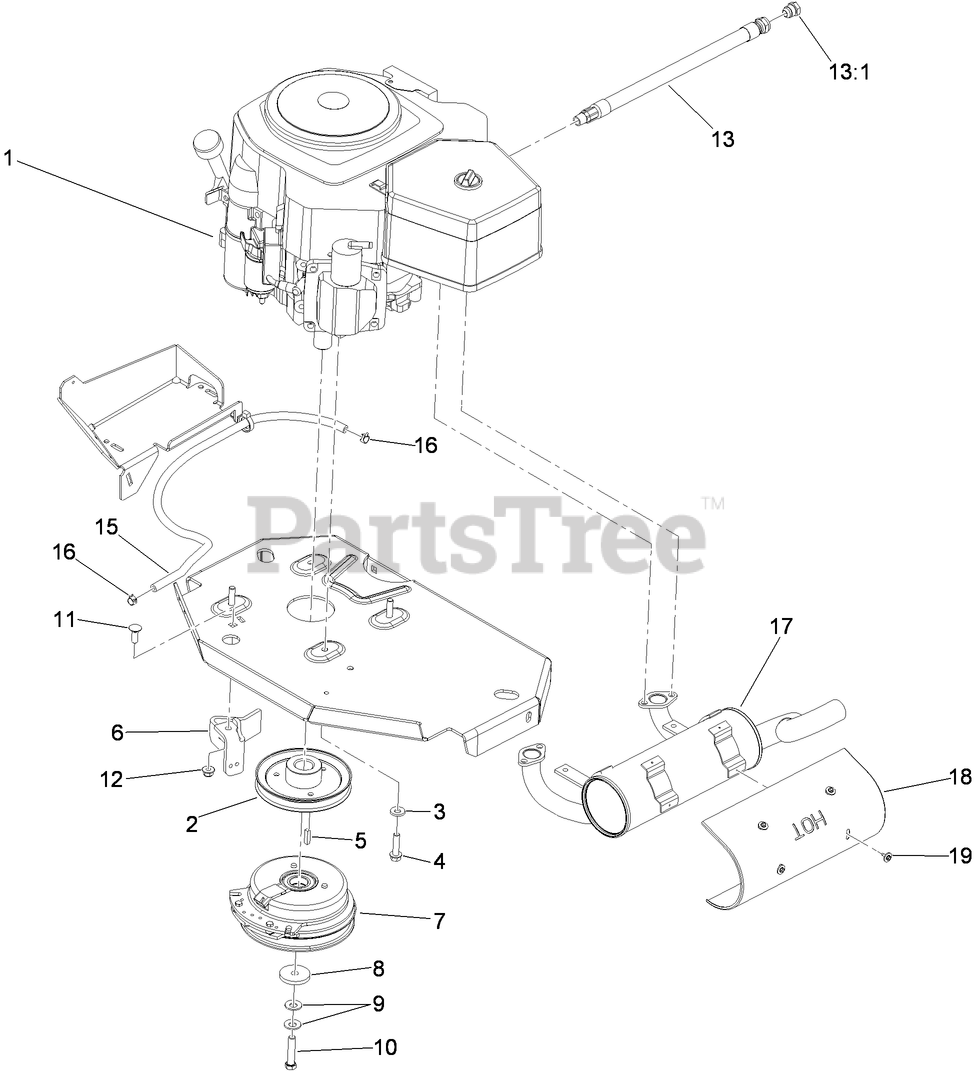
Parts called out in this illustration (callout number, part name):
2	SHEAVE
3	WASHER-BELLEVILLE
4	SCREW-HWH
6	CLUTCH-ANCHOR
7	CLUTCH KIT
8	WASHER-CLUTCH
9	WASHER-SPRING
10	SCREW-HH W/LOCTITE
11	SCREW-CARR
12	NUT-HF, NI
13	OIL DRAIN HOSE ASM
15	HOSE-FUEL
16	CLAMP-HOSE
17	MUFFLER
18	GUARD-MUFFLER
19	SCREW-HH, THREAD FORMING
